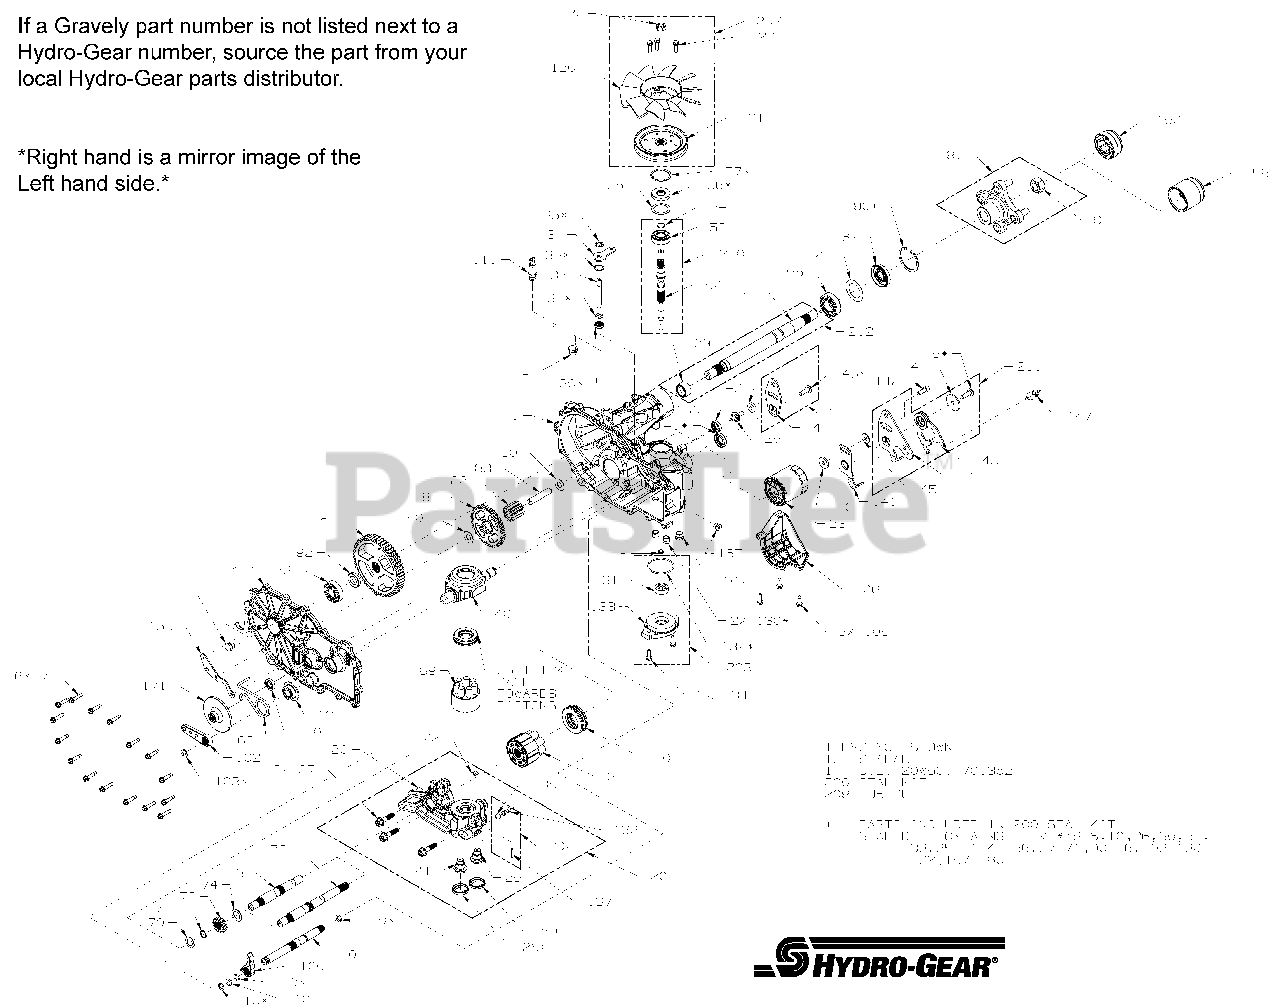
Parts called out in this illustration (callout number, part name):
1	KIT, HOUSING, MAIN, RH, CHRG, CNTL
2	KIT, COVER, SIDE, RH
7	SCREW,HEX WASHER 1/4-20X1.125
13	SEALANT TUBE 10.1OZ.
22	PLATE, BYPASS
23	OIL FILTER, TRANSMISSION
26	SEAL, PLUG 1.375 X .250
30	SEAL, LIP .375X.75X.25
31	RING. RETAINING
32	ROD, BYPASS
33	RING, RET .750
34	ARM, BYPASS
35	RING, RTNG .
40	TRUNNION, SWASHPLATE
41	SEAL, LIP 18X32X7
45	WASHER
46	TWHCS 5/16-24 X 1.00
55	WASHER 1.23X1.56X.04
56	SEAL, LIP 17X40X7
57	RING, RET 1.56 INT
60	HG THRUST BEARING (51462)
64	HG 16CC CYLINDER BLOCK (71579)
65	BEARING. THRUST 30 X 52 X 13
69	ASSY, BLOCK 7 PISTON
70	WASHER .63X1.0X.05
71	RING, RET 62 EXT
72	GEAR, 13T, STEEL
73	SHAFT, MOTOR
74	WASHER .71 X 1.16 X .04
80	WASHER .5X1.0X.032
82	GEAR, 11T, STEEL
83	JACK SHAFT (PIN)
90	RING, RETAINING
95	BEARING, BALL 25.4 X 52 X 15
96	SEAL, LIP
97	HUB, HYDROGEAR P/N 71691
99	NUT, HEX, LOCK 3/4-16
100	PAWL, BRAKE
101	KIT, BRAKE SHAFT
102	BRAKE ARM HG 71957
103	RING, RETAINING
105	HFHCS 1/4-20X.75
106	GUARD, FILTER, RH
111	KIT, FITTING 1/2 BEADED 9/16
120	FAN, 7.0 W/ INSERT
121	DISC, PULLEY, CUPPED, 4.5 INCH
122	NUT, HEX 1/2-20 PATCH
124	HUB, PULLEY
130	TUBE, CONNECTING
131	GEROTOR
132	O-RING HYDROGEAR 52250
133	COVER, CHARGE PUMP
134	HFHCS 1/4-20X.75
140	SPACER
141	ARM, NEUTRAL RIGHT
142	SHCS 5/16-24X1 PATCH
147	SPRING, EXTNSN RTN - 34 LBS
156	CAP, AXLE
157	KIT, GEROTOR SEAL
159	SPRING, TORSION, CW
164	SPACER
200	KIT, SEAL
201	KIT, CENTER SECTION RH, CHRG
202	KIT, CHARGE RELIEF
203	KIT, CHARGE PUMP 71411
207	PULLEY/FAN KIT HG P/N 71694
209	HUB PULLER 4 BLT HYDGEAR 71459
210	INPUT SHAFT 2800 HYDGEAR 71442
211	RTN KIT HYDROGEAR P/N 71597
212	KIT, SHAFT, AXLE
